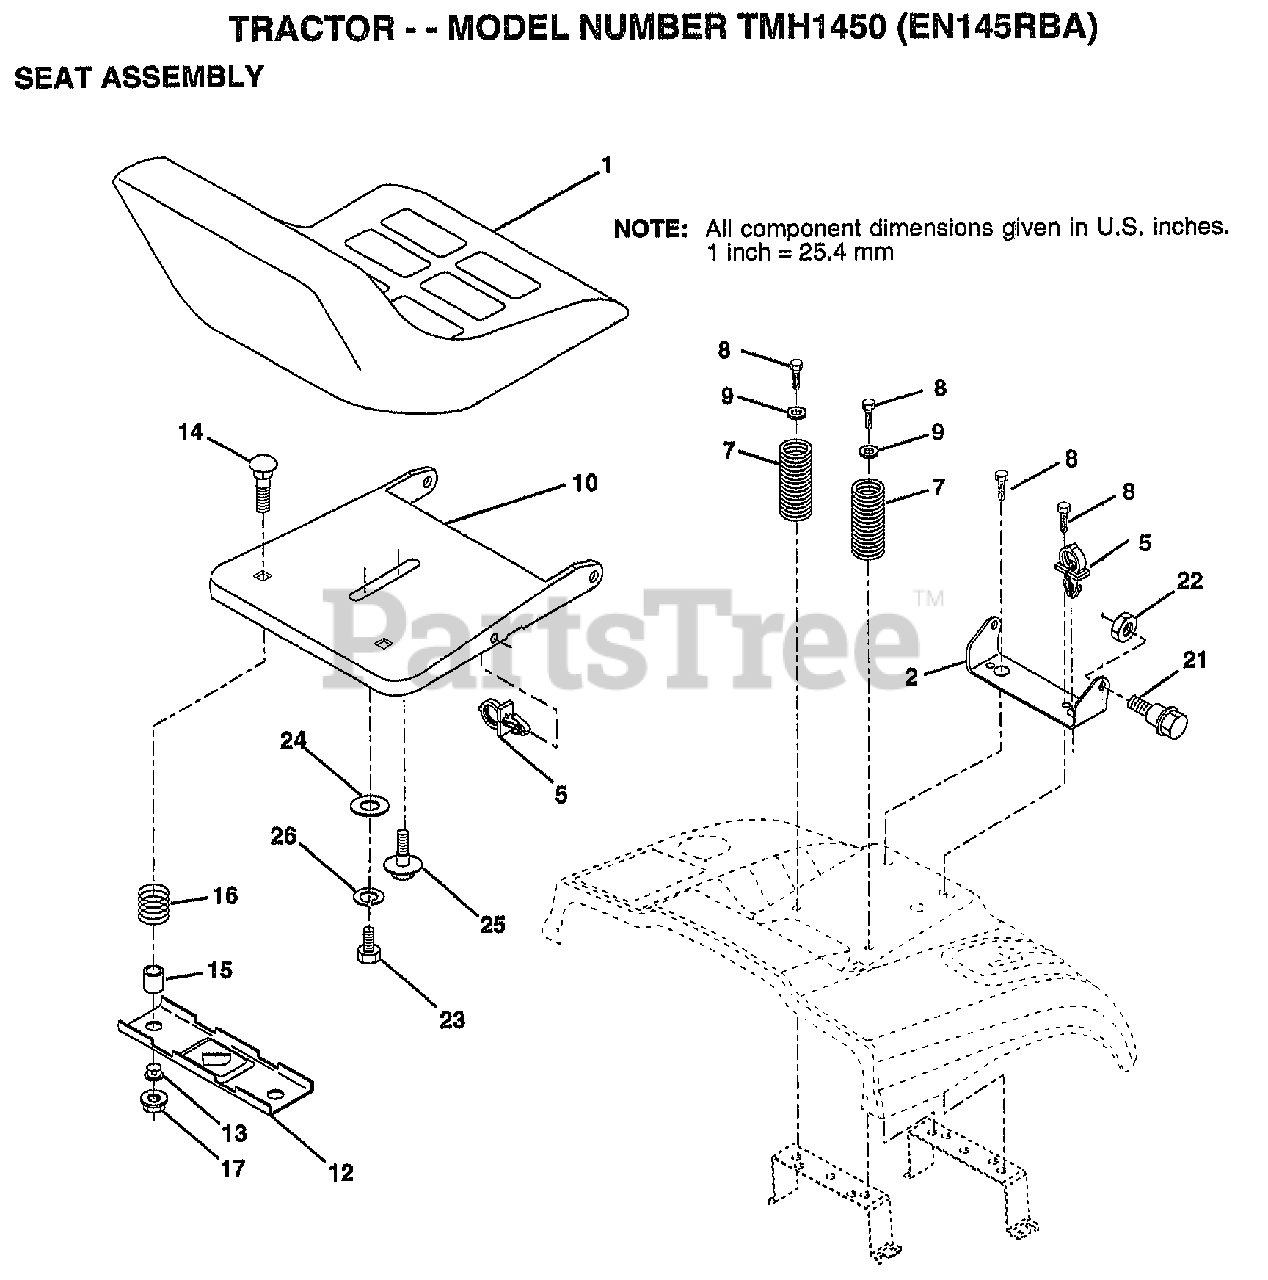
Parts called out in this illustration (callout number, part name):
2	BRACKET PVT SEAT
5	CLIP.PUSH-IN.HING
7	SPRING COMPRESSIO
8	SCREW GTV
9	WASHER
10	PAN-SEAT
12	BRKT SWITCH
13	BUSHING
14	BOLT-RD HD SQ NK
15	SPLIT SPACER
16	SPRING
21	"BOLT,SHOULDER"
22	NUT
23	BOLT
24	WASHER
25	"BOLT,SHOULDER"
26	LOCKWASHER
